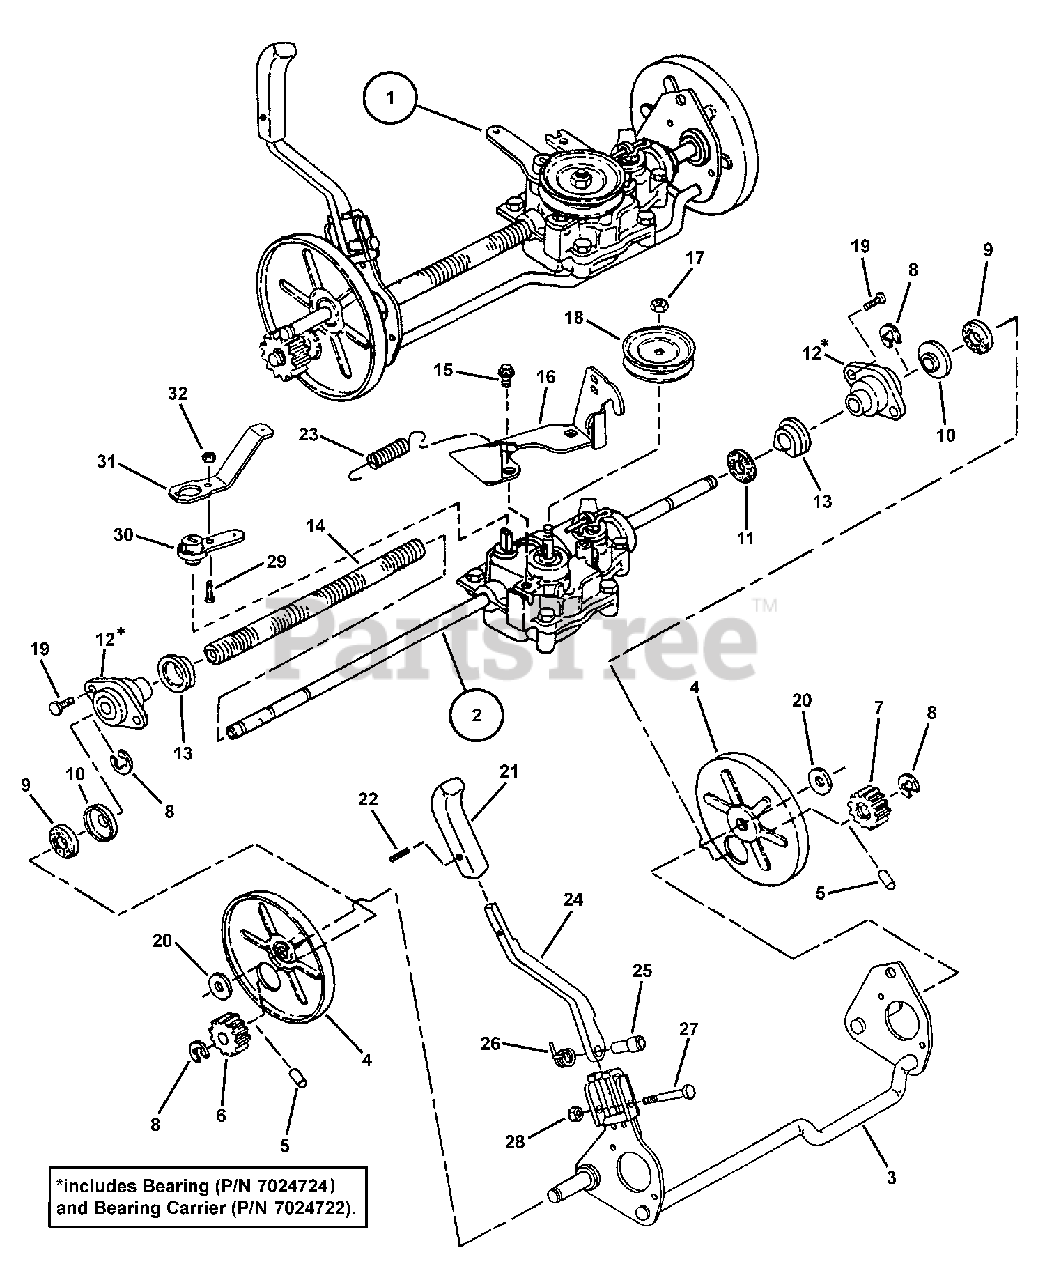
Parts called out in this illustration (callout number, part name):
1	AXLE/TRANSMISSION ASSY (Not Available)
2	TRANSMISSION ASSY, 3SP Commercial
3	WELDMENT, Rear Axle
4	SHIELD, Dust
5	PAWL, 3/16" O.D.
6	PINION, RH Drive
7	PINION, LH Drive
8	RING, External Retaining
9	SEAL, Pinion (Felt)
10	RETAINER, Pinion Seal
11	WASHER, Felt
12	ASSEMBLY, Bearing Carrier
13	BUSHING, Rear Axle (S/P)
14	TUBING, 5/8 I.D. Convoluted
15	SCREW, 5/16-18 x 5/8" Hex Washer Head, Self-Tap
16	BRACKET, Transmission
17	NUT, M10 x 1.50 Hex Nyloc
18	PULLEY, Transmission
19	SCREW, 1/4-20 x 3/8" Hex Washer Head, Self-Tap
20	WASHER, 17/32" Flat
21	KNOB, Height Adjusting Lever
22	ROLL PIN, 3/16 x 3/4"
23	SPRING, Clutch
24	HANDLE, Lift
25	SPACER, .37 x .5 x .44
26	SPRING-Torsion Return
27	SCREW, 1/4-20 x 2" Hex Head Cap GR 5
28	NUT, 1/4-20 Hex Nyloc
29	*SCREW, #10-24 x 5/8" Slotted Hex Washer Head Self-Tap
31	* LEVER, Transmission (Metal)
32	*NUT, #10-24 Hex Center Lock
